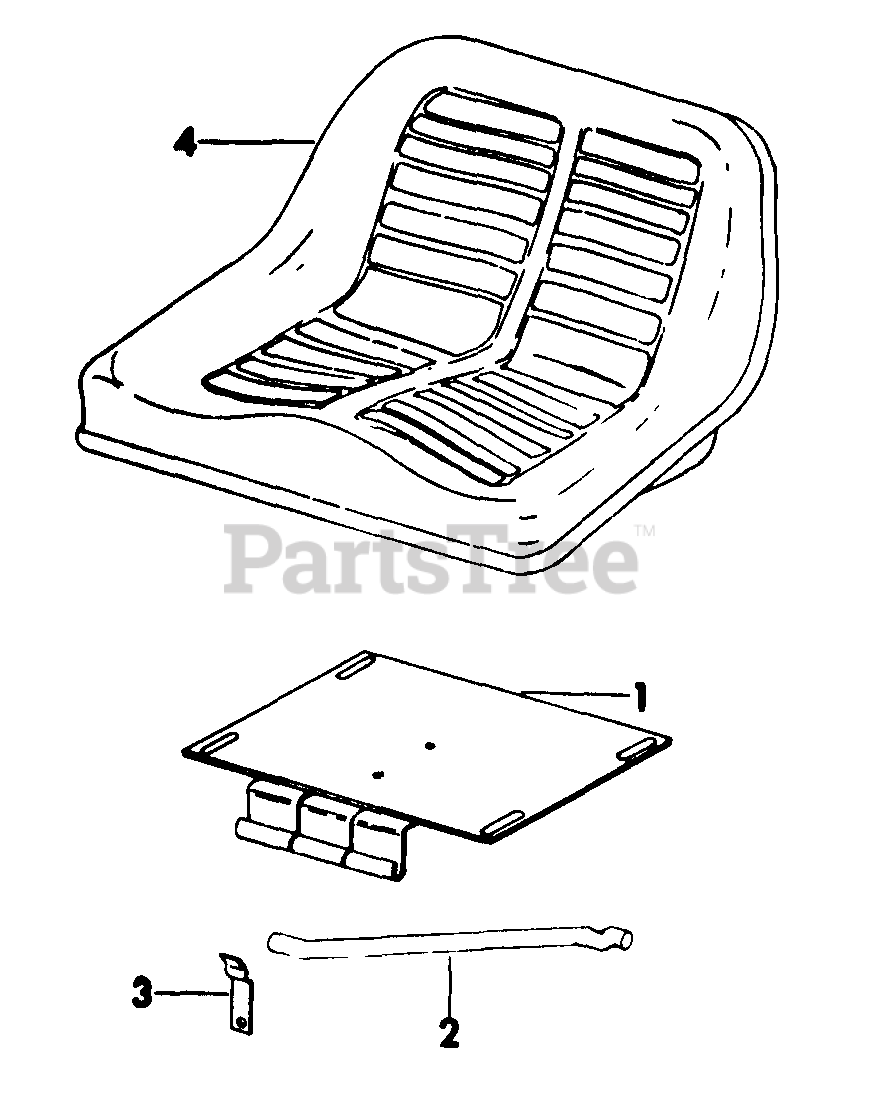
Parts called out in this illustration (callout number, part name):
1	PLATE ASSY, SEAT SUPPORT
2	ROD, SEAT SUPPORT
3	CLIP, HOLD DOWN
4	SEAT
